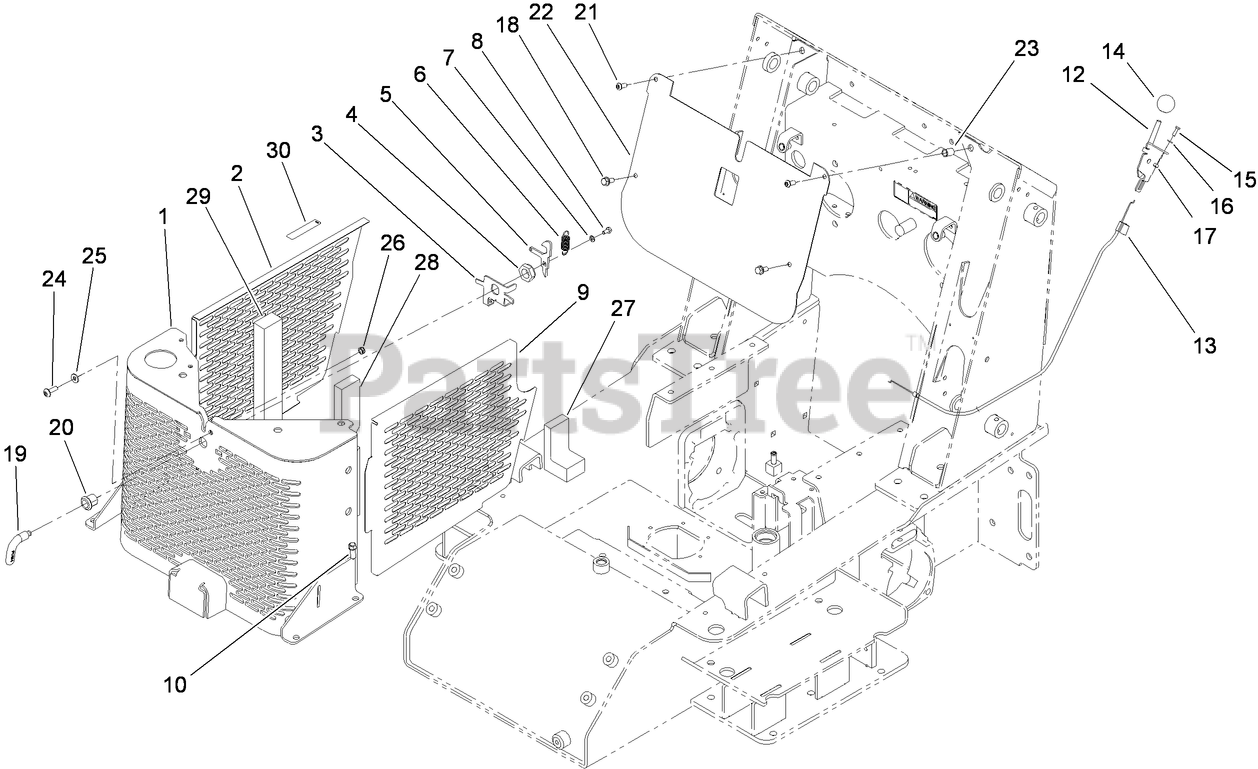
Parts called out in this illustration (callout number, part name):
1	GRILL ASM
2	PANEL-SIDE, RH
3	BRACKET-LATCH
4	NUT-LOCK, NI
5	CAM-LATCH
6	SPRING
7	WASHER-LOCK
8	SCREW-HH
9	PANEL-SIDE, LH
10	SCREW-TAPTITE
12	LEVER-CONTROL
13	CABLE-THROTTLE
16	WASHER-FLAT
17	NUT-LOCK, NI
18	SCREW-HHF
19	HANDLE-LATCH
20	HOUSING-LATCH
21	SCREW-HSBH
22	BAFFLE-ELECTRICAL
23	INSERT-THREADED
24	SCREW-PTH
25	WASHER-FLAT
26	NUT-LOCK, NI
27	SEAL-FOAM
28	SEAL-FOAM
29	SEAL-FOAM
30	DECAL-WARNING, FAN
